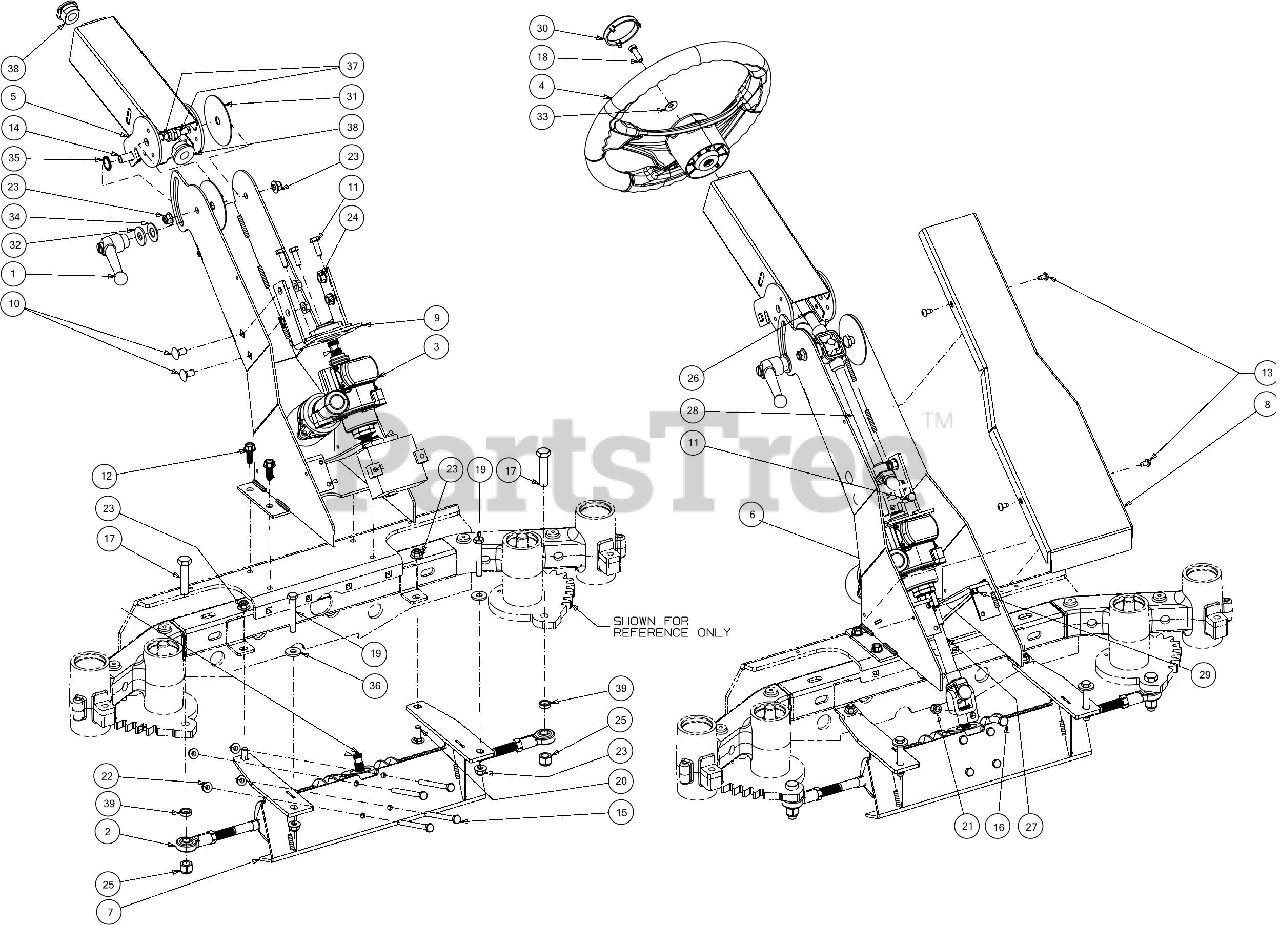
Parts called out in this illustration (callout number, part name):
1	LEVER - ADJ STEERING
2	STEERING GEARBOX
3	POWER ASSIST STEERING ASSEMBLY
4	STEERING WHEEL
5	UPPER PIVOT COLUMN
6	BASE COLUMN
7	STEERING RACK MOUNT
8	FRONT COLUMN COVER
9	POWER STEERING MOUNT
10	CARRIAGE BOLT 3/8-16 X .750 GR5
11	SCREW M8-1.25 X 25 GR8.8
12	SCREW 3/8-16 X 1
13	SCREW 1/4-20 X .5
14	CARRIAGE BOLT 1/2-13 X 1.25 GR5
15	SCREW 5/16-18 X 4.00 GR5
16	SCREW 3/8-16 X 1.50 GR8
17	SCREW 1/2-20 X 2.25
18	SCREW 5/16-18 X 1.00 GR5
19	HEX SCREW-3/8-16X2.5 GR5
20	CARRIAGE BOLT 3/8-16 X 1.00 GR5
21	HEX NUT INS L-3/8-16
22	FLANGE LOCK NUT 5/16-18
24	HEX LOCK NUT
25	HEX NUT 1/2-20 GR8 NYLON
26	RETAINING RING
27	STEERING SHAFT
28	STEERING SHAFT
29	CABLE TIE 7"
30	STEERING WHEEL CAP
31	COLUMN PLATE
32	FLAT WASHER
33	BELL WASHER .337 X.867 X .057
34	FLAT WASHER NYLON 5/8
35	LOCK WASHER
36	FLAT WASHER .406ID X1.0 OD
37	SHOULDER SCREW .498 DIA X .340
38	FLANGE BEARING
